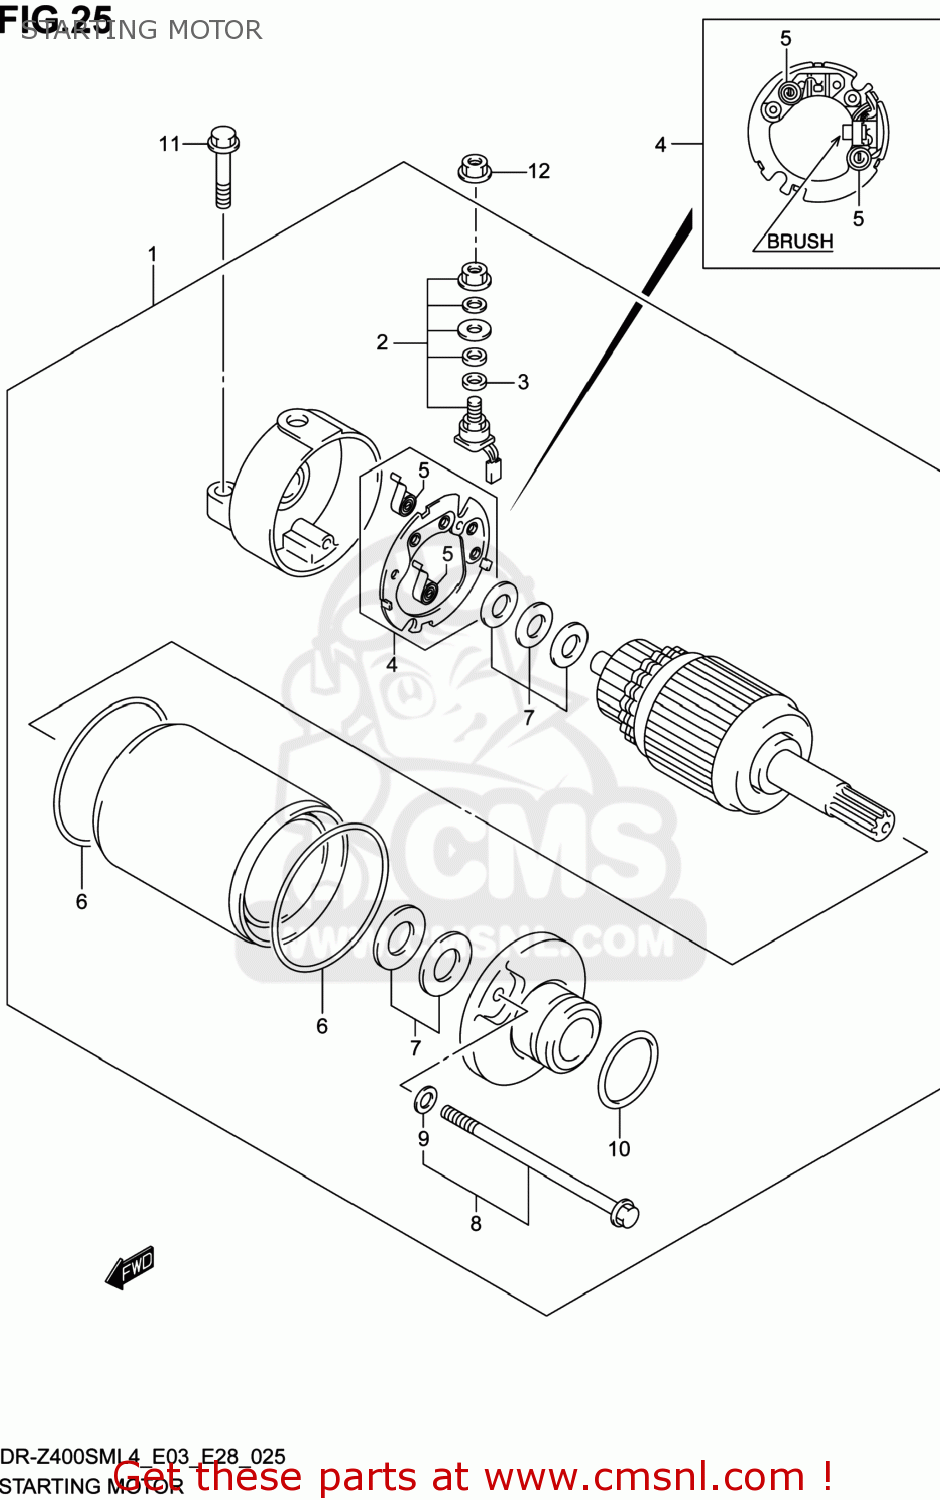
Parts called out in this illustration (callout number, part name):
1	MOTOR ASSY,STARTING
2	BRUSH TERMINAL SET
3	O RING
4	BRUSH HOLDER SET
5	SPRING,BRUSH
6	O RING
7	SHIM SET,STARTING MOTOR
8	BOLT SET
9	O RING
10	O RING(D:3,ID:24.5)
11	BOLT(6X25)
12	NUT
